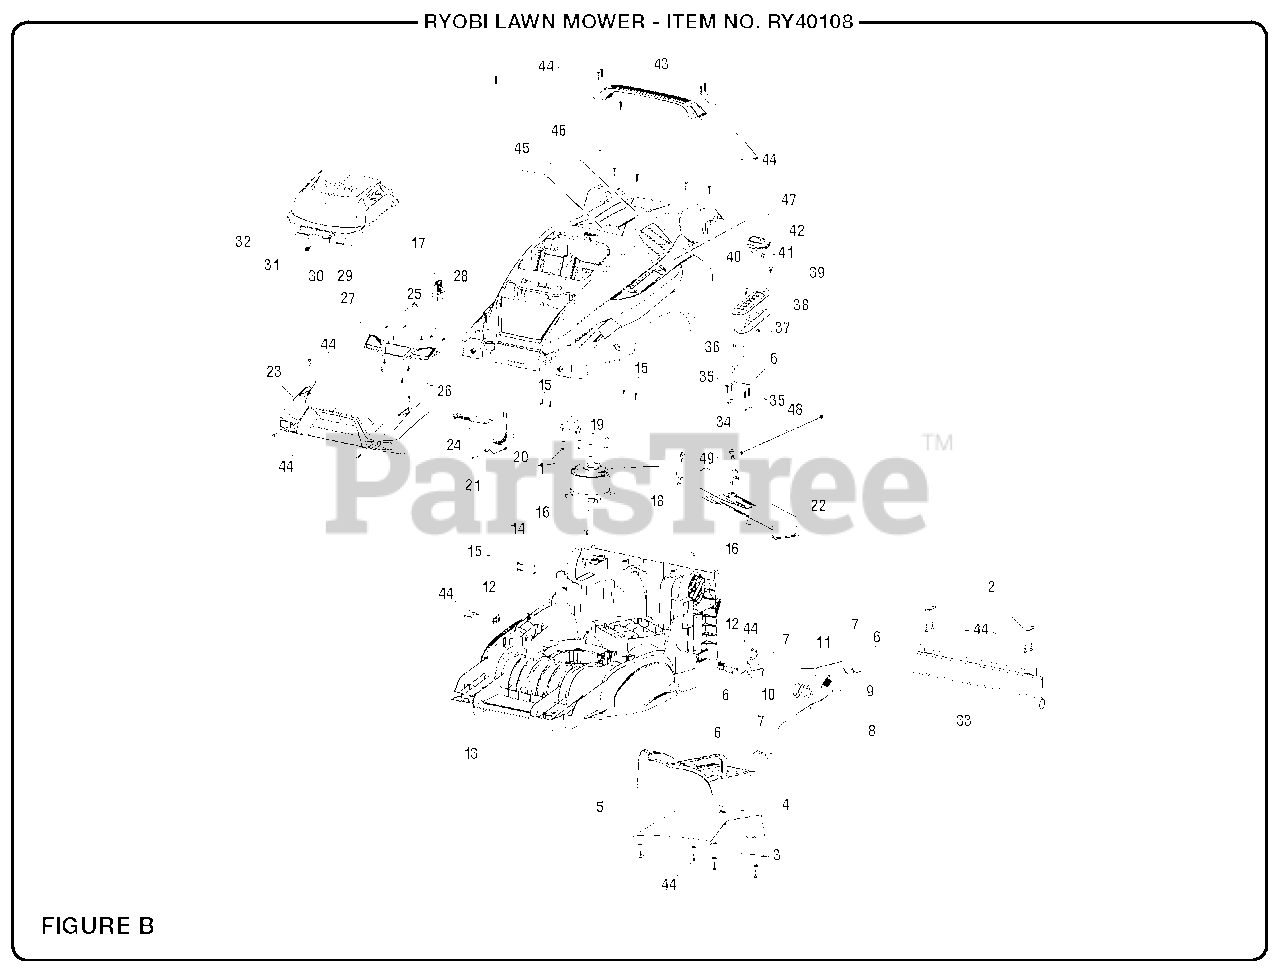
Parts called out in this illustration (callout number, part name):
1	Washer (ID6.2 x OD15 x 0.08t)
2	Axle Pressure Plate
3	Washer (ID4.5 x OD10 x 1t)
4	Rear Cover
5	Mulching Plug
6	Cotter Pin
7	Washer (ID8.4 x OD18 x 1t)
8	Front Lift Rod
9	Torsion Spring (Height Adjustment)
10	Height Adjustment Bracket
11	Rear Lift Rod
12	Axle Mount
13	Deck
14	Cord Clip
15	Screw (M4 x 16 mm, T20 Torx Pan Hd.)
16	Square Nut (M8)
17	Start Key
18	Motor
19	Hex Nut (M6)
20	Key Holder
21	Terminal w/Wire
22	Motor Controller
23	Front Bumper
24	Circuit Board (Light Assembly)
25	Screw (M3 x 8 mm, Pan Hd., Pan Hd)
26	Screw (M4 x 10 mm, T20 Torx Pan Hd.)
27	Light Assembly
28	Deck Cover
30	Compression Spring
31	Torsion Spring
32	Battery Cover
33	Rear Protective Guard
34	Pressure Plate (Height Adjustment)
35	Screw (M4 x 18 mm, T20 Torx Pan Hd.)
36	Height Adjustment Lever
37	Hex Lock Nut (M5)
38	Dust Gasket
39	Height Adjustment Plate
40	Screw (M5 x 16 mm, Soc. Hd.)
41	Screw (M3 x 7 mm, Flat Hd.)
42	Height Adjustment Handle
43	Carrying Handle
44	Screw (M4 x 20 mm, T20 Torx Pan Hd.)
45	Danger/Warning Icon Label (English)
46	Bilingual Danger (French/Spanish) & Trilingual Warning (English/French/Spanish) Label
47	Height Adjustment Label
48	Inner Wire Connector
49	Terminal Block w/Screw
